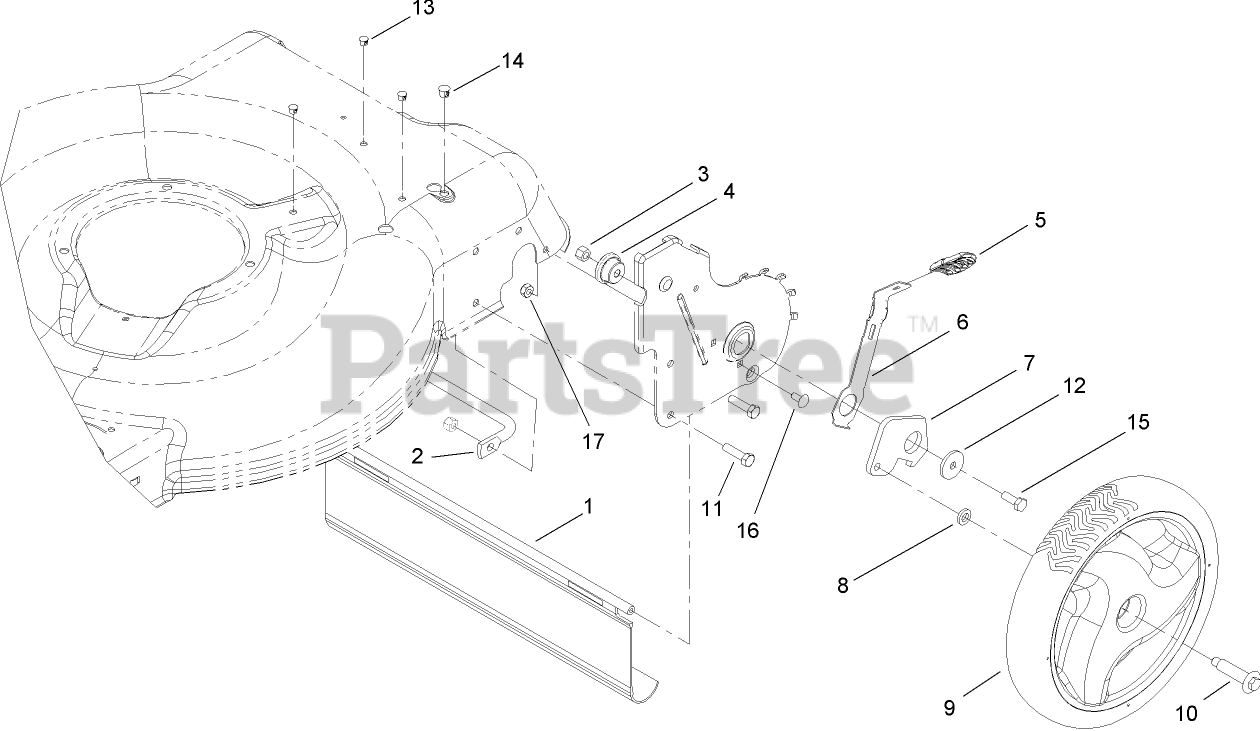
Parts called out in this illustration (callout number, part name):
1	SHIELD-TRAILING
2	BRACE-PLATE, HOC
3	NUT-HEX, SIDE DEFORM
4	BUSHING-MOUNT
5	KNOB-LEVER, HOC
6	ARM-11 INCH SPRING, REAR
7	ARM-PIVOT, REAR (LH)
8	WASHER-BOLT, WHEEL
9	11 INCH WHEEL ASM
10	BOLT-SHOULDER
11	SCREW-HH
12	WASHER-FLAT
13	PLUG-DOME
14	PLUG-DOME
15	SCREW-HH
16	SCREW-CARR
17	NUT-LOCK, NI
